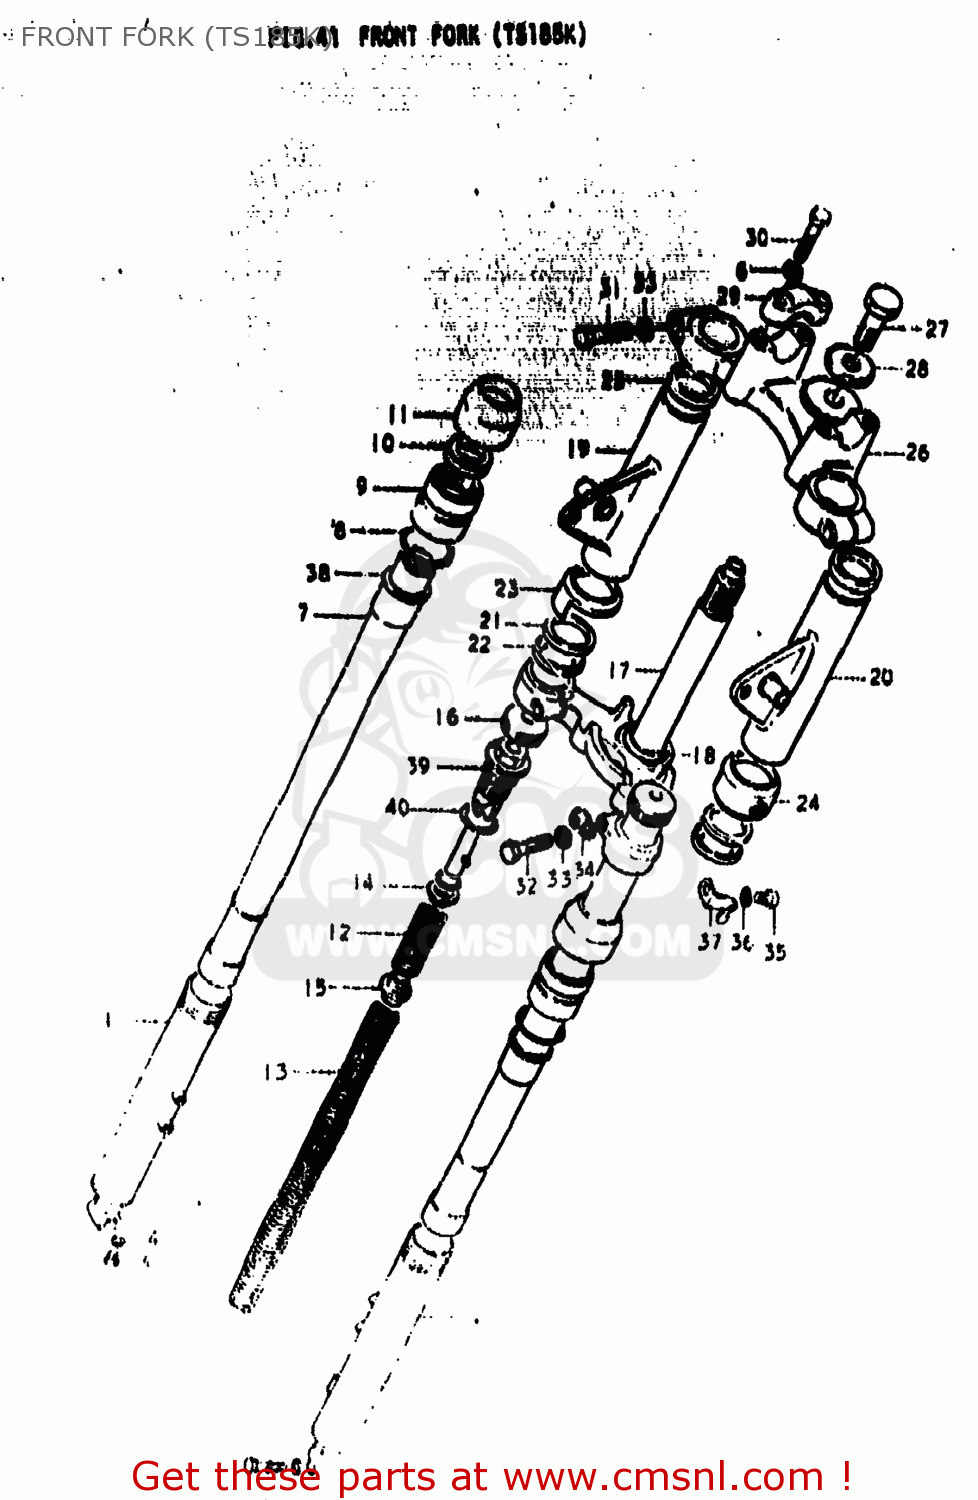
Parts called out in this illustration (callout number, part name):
1	TUBE,OUTER,RIGHT
2	TUBE,OUTER,LEFT
3	SCREW
4	GASKET,DRAIN,PLUG (NAS)
5	BOLT
6	LOCK WASHER
7	TUBE,FORK,INNER
8	O RING,OIL SEAL LWR
9	NUT,FORK OUTER TUBE
10	SEAL,OIL
11	SEAL,DUST
12	SPRING
13	SPRING,FRONT FORK
14	GUIDE,SPRING
15	JOINT,SPRING
16	CAP,FRONT FORK
17	STEM,STEERING
18	RACE,STEERING OUTER LWR
19	BRACKET,HEADLAMP HOUSING
20	BRACKET,HEADLAMP,LEFT
21	CUSHION,HEADLAMP BRACKET
22	GUIDE, COVER
23	CUSHION,HEADLAMP BRACKET
25	SEAT,HEADLAMP BRACKET
26	HEAD,STEERING STEM
27	BOLT,FORK INNER TUBE
28	WASHER
29	HOLDER,HANDLEBAR
30	BOLT
31	BOLT,FORK INNER TUBE F
32	BOLT,FORK INNER TUBE F
33	LOCK WASHER
34	GUIDE,CABLE
35	SCREW
36	LOCK WASHER
37	CLIP
38	BUSHING,GUIDE
39	CAP
40	SEAT,SPRING
